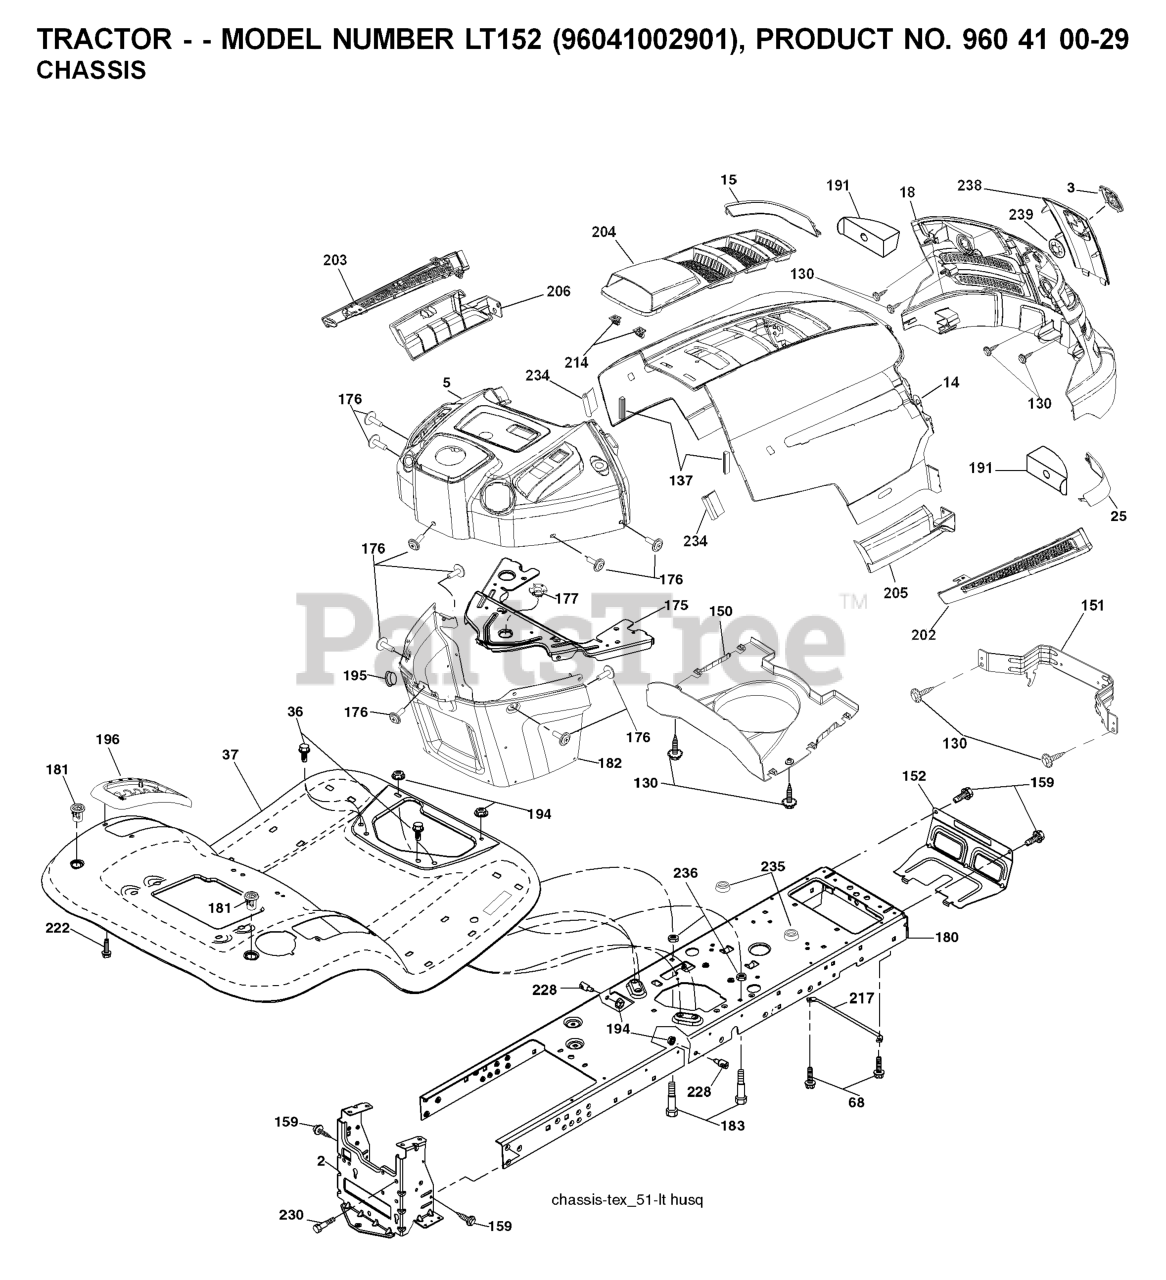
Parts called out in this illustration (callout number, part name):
2	DRAWBAR.1PC.NSTL
3	RP LOGO
5	DASH
14	HOOD
15	LENS.HUSQVARNA LT.LH
18	RP GRILLE/LENS ASM.
25	LENS.HUSQVARNA LT.RH
36	SCREW 5/16"
68	Screw 5/16-18 x 1/2 Hex, Self Tapping 5/16-18 x 1/2
130	SCREW
137	BUMPER DASH
151	BRACKET PIVOT
152	SHIELD.BROWNING/DEBRIS
159	SCREW, 3/8-16X3/4
175	CROSSMEMBER
176	SCREW.#10-24X5/8.RN.QU
177	BUSHING STEERING
180	CHASSIS.STAMPING.LT/GT
181	BUSHING.MNT.FEND.CRGO.
182	DASH LOWER
183	BOLT.5/16-18X1-1/4 FULL.THREAD
191	INSERT REFLECTIVE
194	NUT LOCK HEX FLANGE 5/16-18
195	PLUG DASH
196	CONSOLE.ASM.DECK.LIFT.
202	VENT SIDE HOOD RH
203	VENT SIDE HOOD LH
204	VENT TOP HOOD
205	SKIRT SIDE RH
206	SKIRT SIDE LH
214	CLIP.RETAINER.TINNER.
217	ROD PIVOT CHASSIS/HOOD
219	STUD.FASTNER.W/ANTI-ROTATE
222	SCREW.1/4-20X5/8
230	SHOULDER BOLT 5/16-18TT
234	BUMPER.HOOD.TEX.HUSQVARNA
235	SPACER FENDER
236	NUT LOCK HEX FLANGE 5/16-18
238	TRIM
